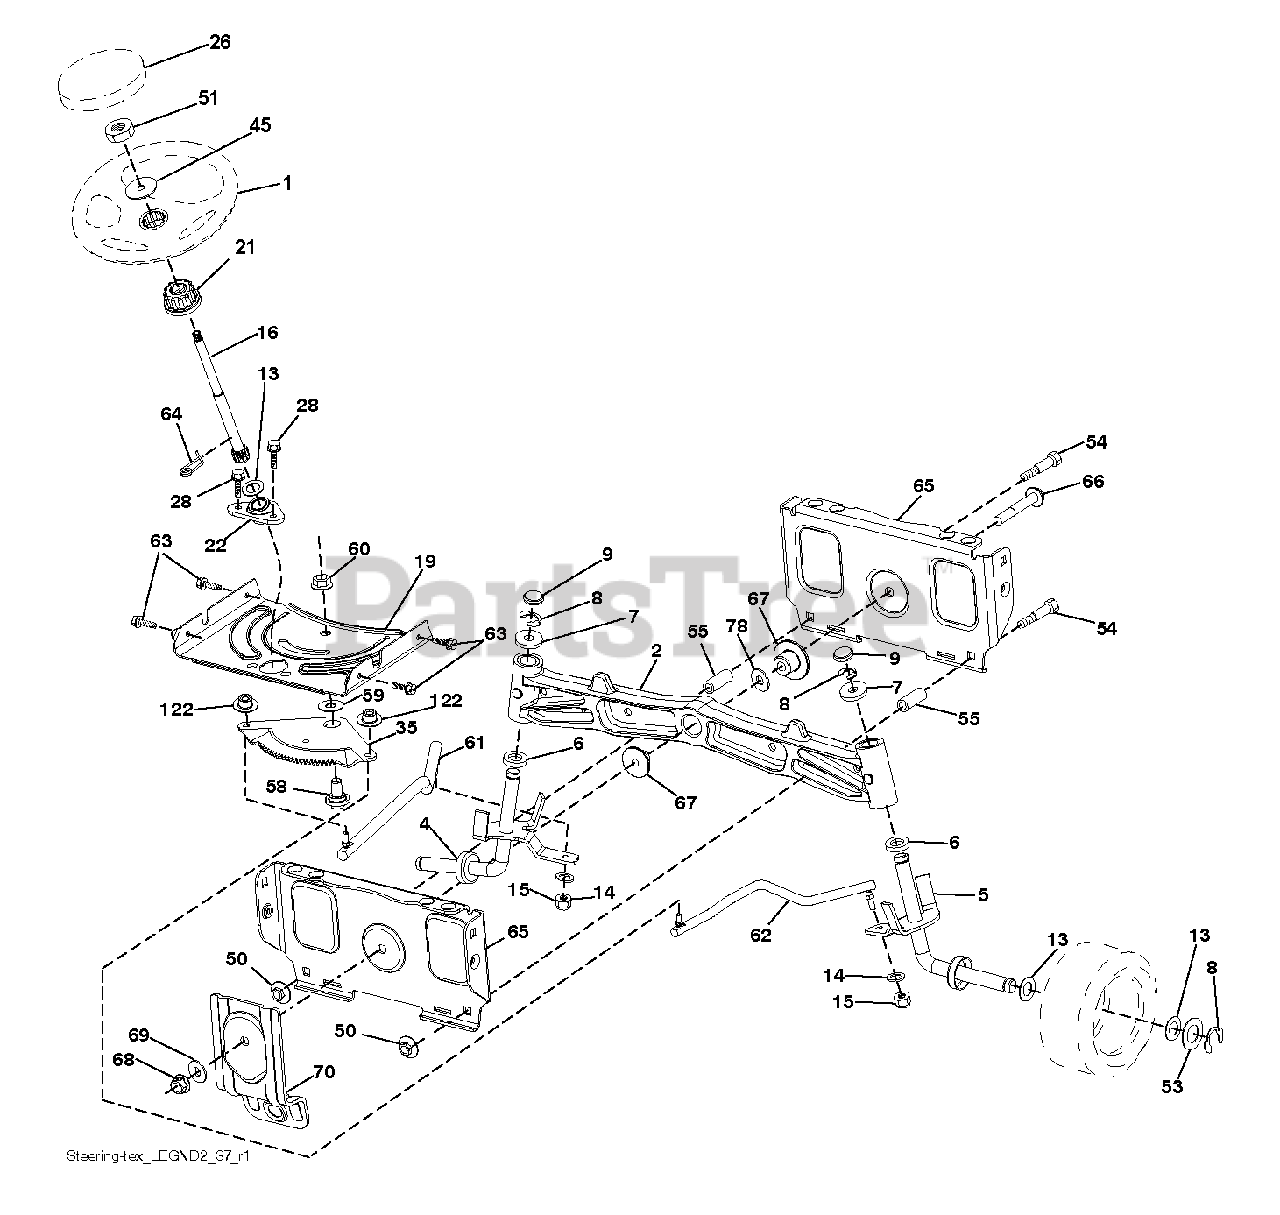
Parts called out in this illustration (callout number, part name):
1	WHEEL.STEER.HUSQ.SR.498.OVMLD
2	AXLE.CAST.IRON
4	SPINDLE.WELDED.LH.16"TEX
5	SPINDLE.WELDED.RH.16"TEX
6	THRUST WASHER
9	CAP.SPINDLE.BLACK
14	WASHER, LOCK 3/8
15	NUT CROWNLOCK 3/8-24
16	SHAFT, STEERING
19	PLATE.STEER.DDL.NLT/NG
21	ADAPTER, WHEEL STNG..
22	STEERING.SUPT.LOWER.
26	INSERT.CAP.WHL.STRG.HUSQ.PREM
28	SCREW, 3/8-16X3/4
35	GEAR.SECTOR.PLATE.DDL.
45	WASHER 9/16"ID, 2 3/8"OD
50	NUT LOCK FLG 3/8-16 UNC
51	NUT.HEX.1/2-20
53	WASHER.HARDENED
55	SPACER.BRACE.AXLE
58	BOLT.SHOULDER.SECTOR.P
59	WASHER.THURST.SECTOR.S
60	NUT FLANGE LOCK 5/8-11
61	DRAGLINK.LH.BALLSTUD.D
62	DRAGLINK.RH.BALLSTUD.D
63	SCREW
64	RETAINER.CLIP.SPRING.S
65	BRACE.AXLE.FRONT.NLT/N
66	BOLT HEX FGHD 7/16-14 X 3 SERR
67	BUSHING.PM.FRONT AXLE
68	NUT.LOCK.FLANGE.7/16
69	WASHER.1.5X.505X.118
70	BRKT.DECK.SUSPENSION.F
78	THRUST WASHER
122	CAP.GEAR.SECTOR.TEX
